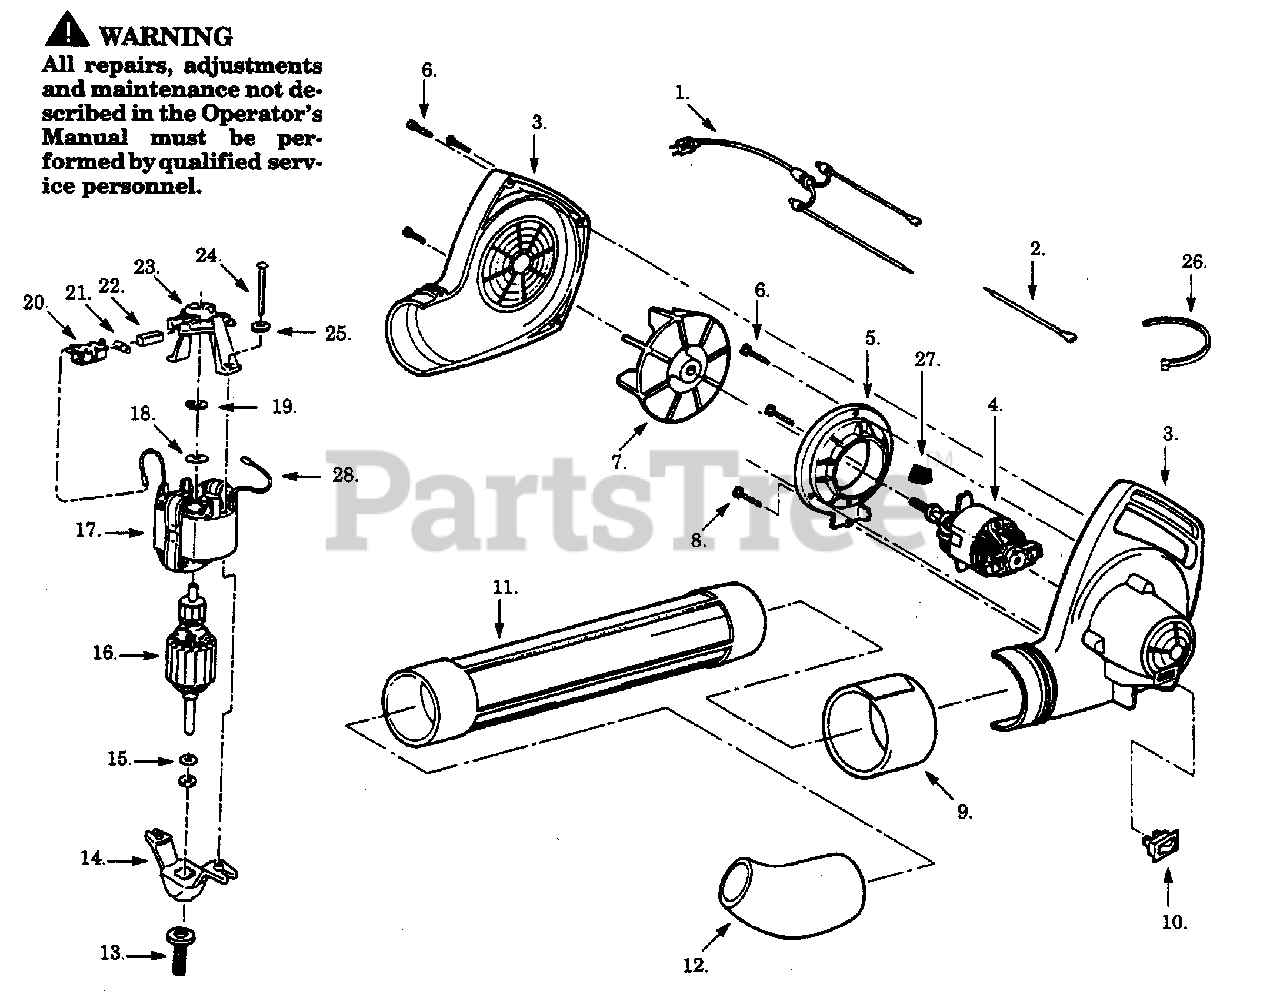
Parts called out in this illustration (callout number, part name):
1	Harness Ass'y.
2	Leadwire Ass'y.
3	Housing Set
4	Motor/Adapter Ass'y.
5	Mounting Plate
7	Impeller
9	Ferrule Sleeve
10	Switch Ass'y.
11	Outlet Tube
12	Curved Nozzle
13	Impeller Adapter
14	Endbell Ass'y. (Drive)
16	Armature Ass'y.
17	Field Ass'y.
19	Retaining Ring
20	Brush Holder
21	Brush Spring
23	Endbell Ass'y.(Brush)
25	Lockwasher
26	Tie Wrap
27	Rubber Spacer
28	Lead Wire
